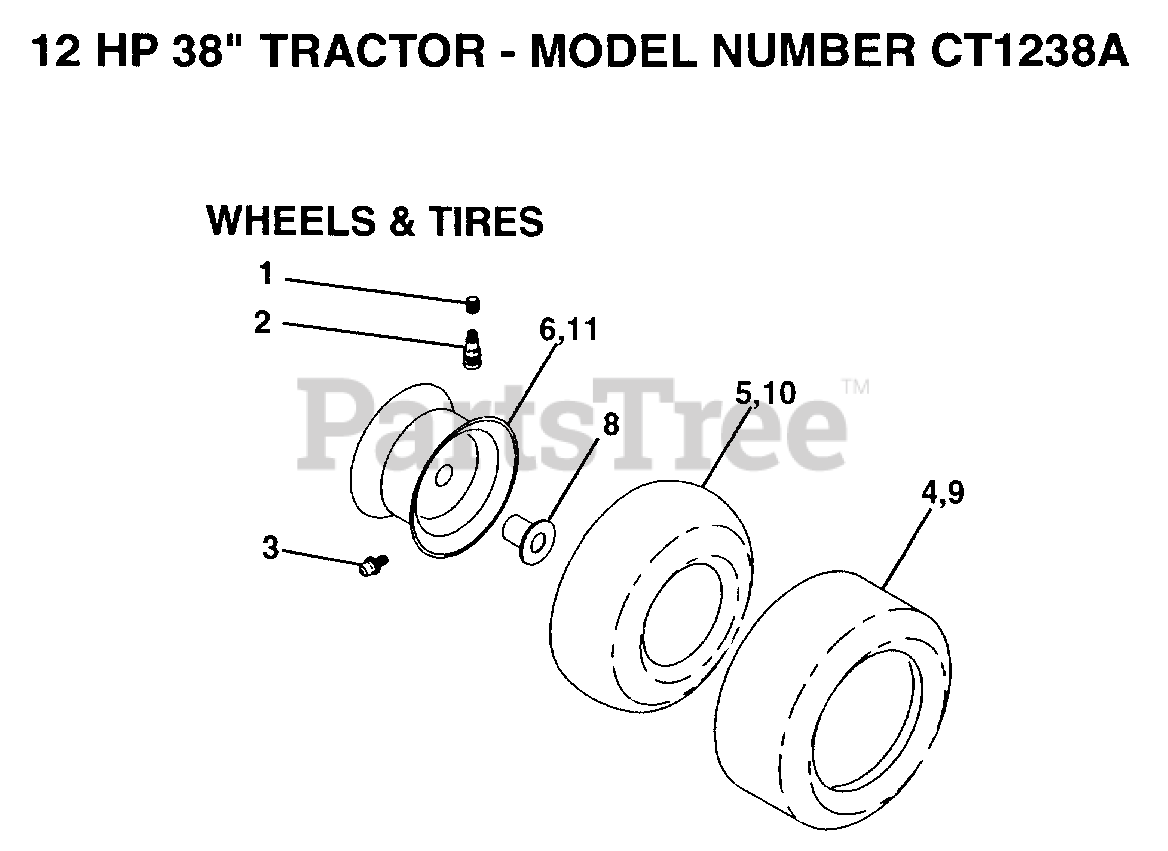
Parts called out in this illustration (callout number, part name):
1	VALVE CAP
2	VALVE STEM LT
3	FITTING LT
4	TIRE.TS2.18X8.5
5	TUBE.5.3/4.5/6
8	"FLANGE, BEARING"
10	TUBE.18X9.5-8
